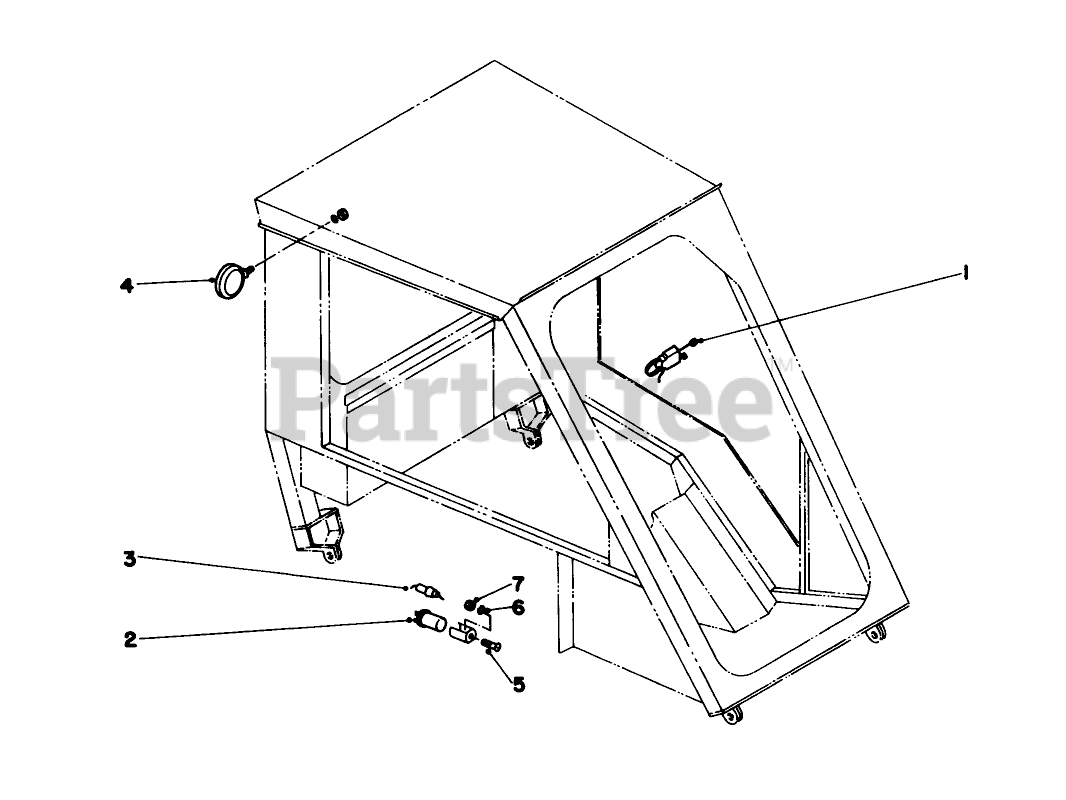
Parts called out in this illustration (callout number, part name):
1	Signal Controller
2	FLASHER
3	Fuse Holder with Fuse
4	Signal & Tail Lights
5	SCREW-PPH
6	WASHER-LOCK
7	NUT-HEX
